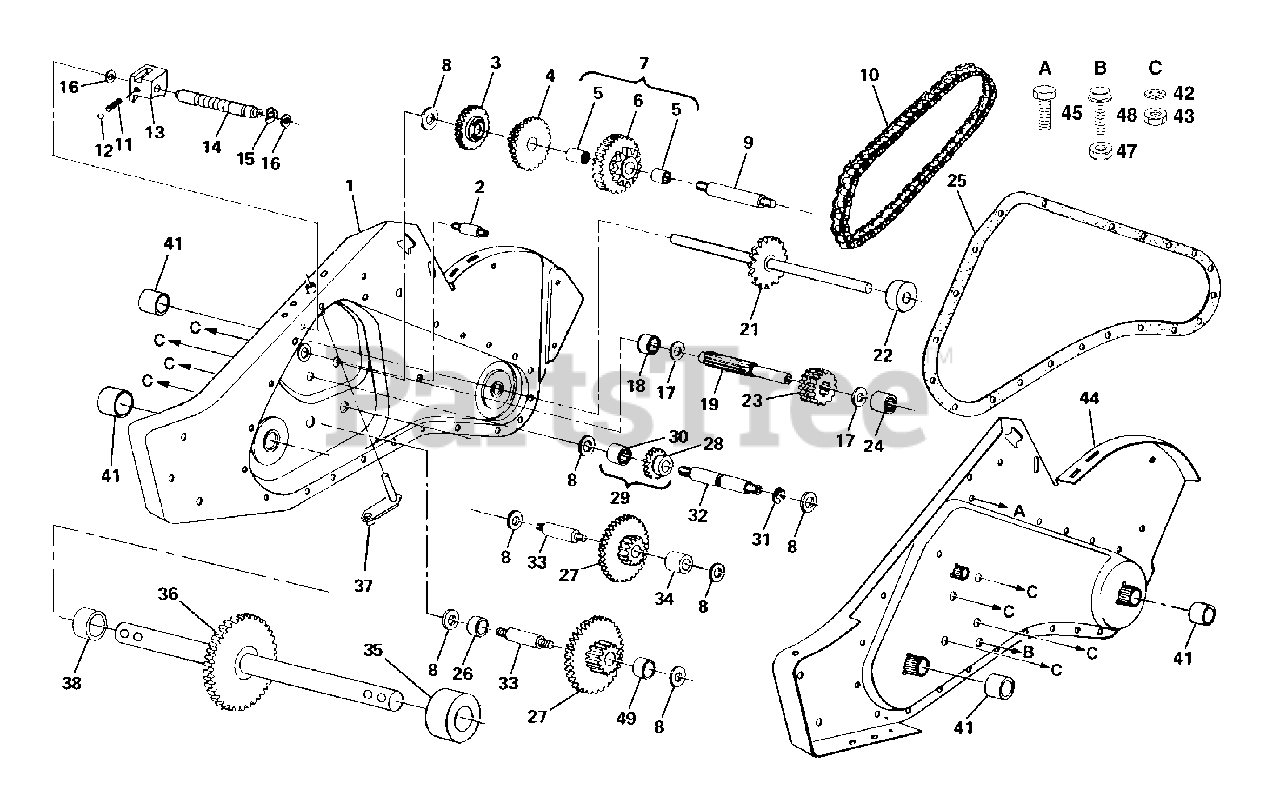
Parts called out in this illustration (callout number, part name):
1	Gearcase Assembly, R.H., with Bearing
2	Bolt, Upset
3	Gear, Reverse
4	Gear, Cluster, Red., 1st and 2nd
5	Bearing, Needle
6	Sprocket Assembly, Tine
7	Sprocket Assembly with Bearings
9	Shaft, Reduction, 1st
10	Chain, Roller, 60P
11	Spring, Shift, Fork
12	Ball, Steel
13	Fork, Shift
14	Shaft, Shift
16	Washer, Seal
17	Race, Bearing, Thrust, 5/8 I.D.
18	Bearing, Needle
19	Shaft, Input
21	Shaft Assembly, Tine
22	Spacer 1.008 x 1-3/4 x .645
23	Pinion, Input
24	Bearing, Needle
25	Gasket, Gearcase
26	Spacer .765 I.D. x 1.12 x 5/8
27	Gear, Cluster, Red., 2nd and 3rd
28	Gear, Reverse Idler
29	Gear Assembly, Reverse Idler
30	Bearing, Needle
32	Shaft, Reverse Idler
33	Shaft, Reduction, 2nd
34	Spacer .765 I.D. x 1-1/8 x 1-3/8
35	Spacer, Ground Drive, L.H.
36	Shaft Assembly, Ground
37	Arm Assembly, Shift
38	Spacer, Ground Drive, R.H.
41	Seal Asm Oil
42	Washer, Lock 7/16
43	Nut, Hex 7/16-20
44	Gearcase Assembly, L.H., with Bearing
45	Screw, Thd Cut 5/16-18 x 5/8
47	Nut, Hex Head 5/16-18
48	Screw, Whiz-Lock 5/16-18 x 4
49	Spacer .765 I.D. x 1.12 x 3/4
